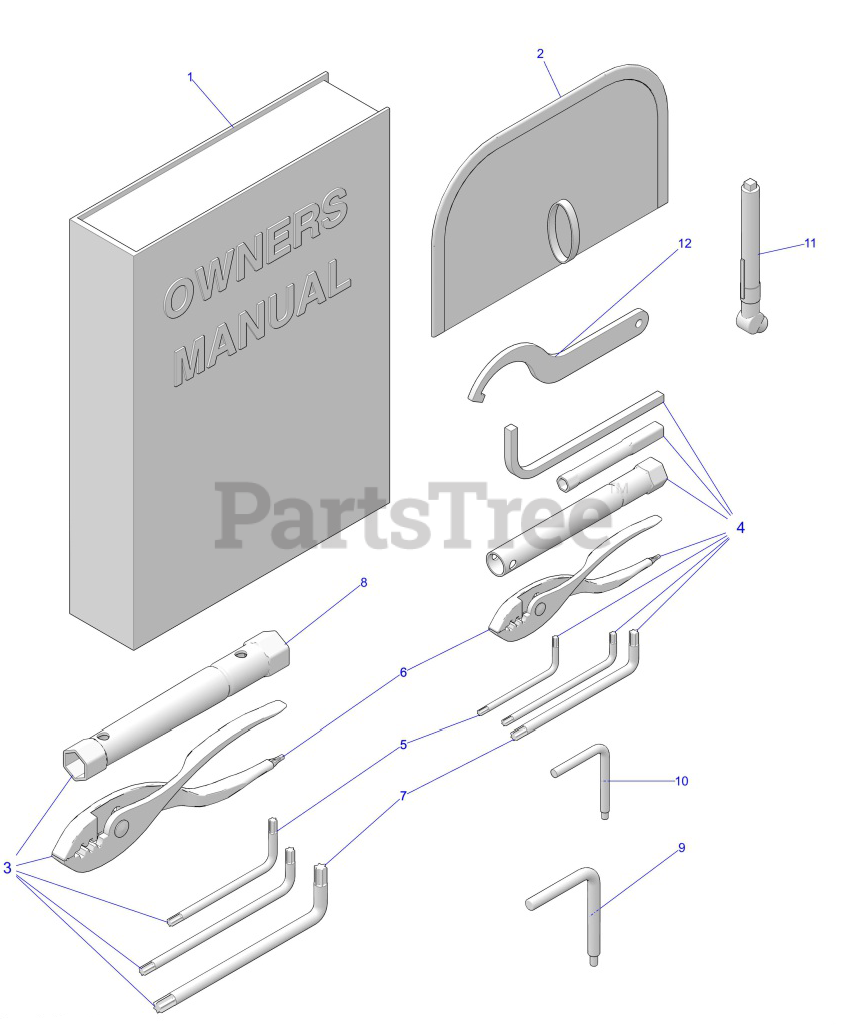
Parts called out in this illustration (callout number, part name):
2	POUCH-TOOLKIT-9"
3	VEHICLE TOOLKIT
4	KIT- TOOL
5	WRENCH-TORX,T-25
6	PLIERS-COMBO, #2 ASSEMBLY
7	WRENCH-TORX-T-40
9	DRIVE CLUTCH SEPARATOR TOOL
10	TOOL-BELT REMOVAL
11	GAUGE-TIRE PRESSURE-30 PSI
12	WRENCH-SPANNER- CAM
